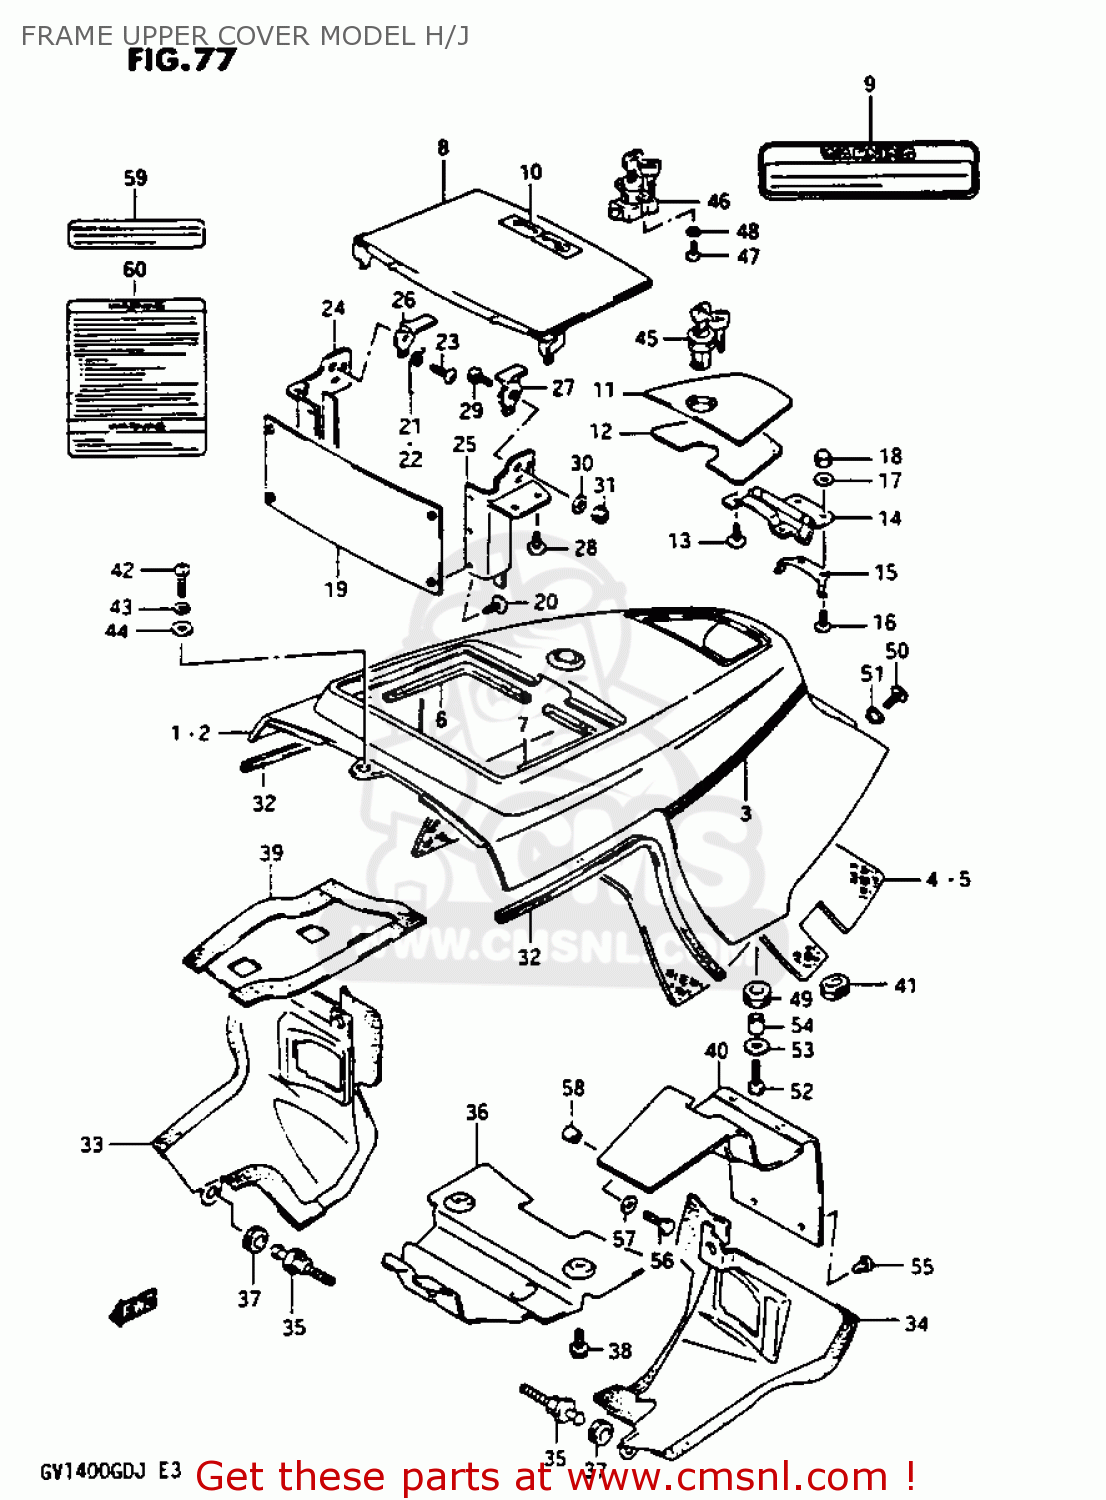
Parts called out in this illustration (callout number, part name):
1	COVER ASSEMBLY,FRAME,UPPER
2	COVER ASSEMBLY,FRAME,UPPER
3	TAPE SET,UPPER COVER SIDE
4	CUSHION,FRAME COVER,UPPER
5	CUSHION,FRAME COVER,UPPER
6	CUSHION,AUDIO LID SIDE
7	CUSHION,AUDIO LID SIDE
8	COVER ASSEMBLY,FRAME,UPPER
9	LABEL (WARNING COVER CO
10	EMBLEM,AUDIO LID
11	LID,FUEL
12	CUSHION,FUEL LID (NA)
13	SCREW 5X8
14	HINGE,FUEL LID
15	SPRING,FUEL LID HINGE
16	SCREW
17	WASHER
18	NUT
19	HOLDER,AUDIO LID
20	SCREW
21	SPRING
22	SPRING
23	SCREW
24	RAIL,RIGHT
25	RAIL,LEFT
26	RAIL PIECE,RIGHT
27	RAIL PIECE,LEFT
28	SCREW, RAIL
29	SCREW
30	WASHER
31	NUT 8MM
32	MOLDING,COVER FRAME,UPPER
33	COVER,INNER,RIGHT
34	COVER,INNER,LEFT
35	BOSS,FRAME COVER
36	COVER COMP,INNER
37	CUSHION
38	BOLT 6X12
39	COVER COMP,UPPER,RIGHT
40	COVER COMP,UPPER,LEFT
41	GROMMET
42	SCREW, 6X20
43	LOCK WASHER
44	WASHER (6.5X18X1.6)
45	LOCK SET,TOOL HOLDER
46	LOCK SET,AUDIO LID
47	SCREW
48	WASHER,LOCK
49	CUSHION
50	SCREW
51	WASHER
52	BOLT
53	WASHER
54	SPACER (6.1X8X9.5)
55	RIVET
56	BOLT
57	WASHER(6.5X16X1.2)
58	SPACER (6.5X12X8)
59	LABEL (WARNING AUDIO BO
60	LABEL (WARNING)
